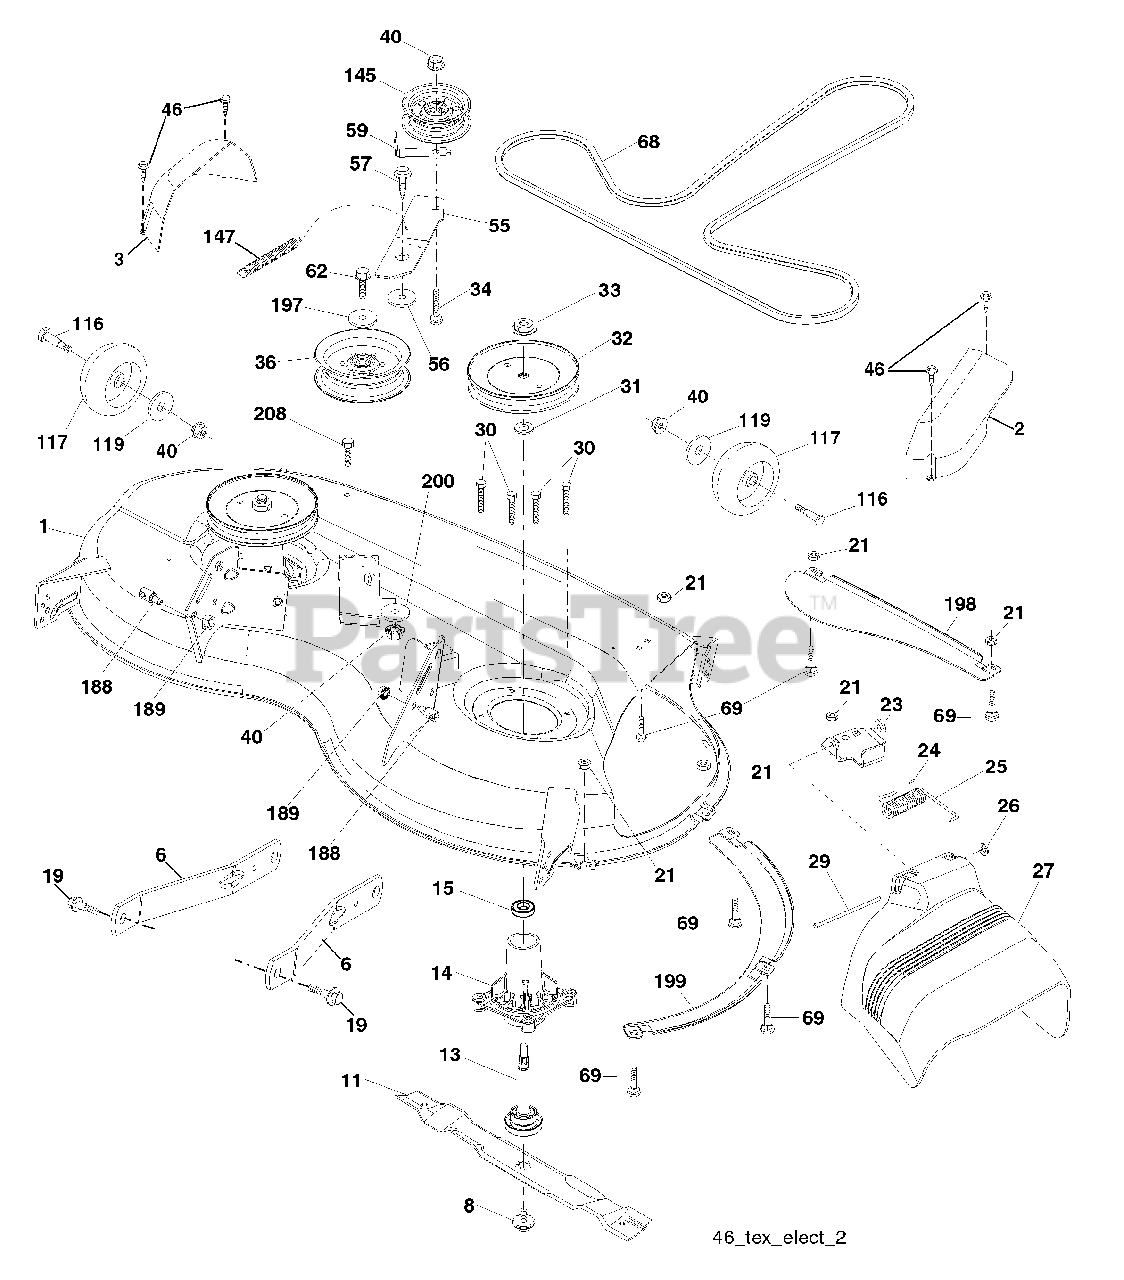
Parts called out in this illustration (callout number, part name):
1	Mower Housing
2	Cover Mandrel LH
3	Cover Mandrel RH
6	Arm Suspension
8	Bolt/Washer asm 7/16-20 unf
11	Blade Mower
13	Shaft Assembly, Mandrel
14	Housing, Mandrel
15	Bearing, Ball, Mandrel
19	Bolt, Shoulder
21	Nut
23	Bracket, Deflector
24	Cap, Sleeve
25	Spring, Torsion, Deflector
27	Shield, Deflector
29	Rod, Hinge
30	Screw Thdrol Rolling Wsh Hd
31	Washer, Spacer
32	Pulley, Mandrel
33	Nut, Toplock, Flanged
34	Bolt Carr Sh.3/8-16 x 1-1/2Gr.5
36	Pulley, Idler, Flat
38	Keeper Belt LH Mandrel
40	Nut 3/8-16 UNC
55	Arm, Idler
56	Spacer, Retainer
57	Screw Hexwsh Thd 3/8-16x1
59	Guard, Tuv Idler
68	V-Belt
69	Bolt
116	Bolt, Shoulder
117	Wheel, Gauge
119	Washer 13/32 x 1-1/4 x 12 Ga.
129	Washer 13/32 x 13/16 x 12 Ga.
145	Pulley Idler
188	Stud Fastener
189	Nut Lock Hex Flange
198	Baffle Center Front
199	Baffle Front RH
200	Washer 13/32 x 1 x 1/2 11 Ga.
208	Screw THDROL 3/8-16 x 1/2
240	Bolt3/8-16 x 2-1/4Gr. 5
240	Mandrel Assembly
240	Blade Mulching
240	Replacement Mower, Complete
